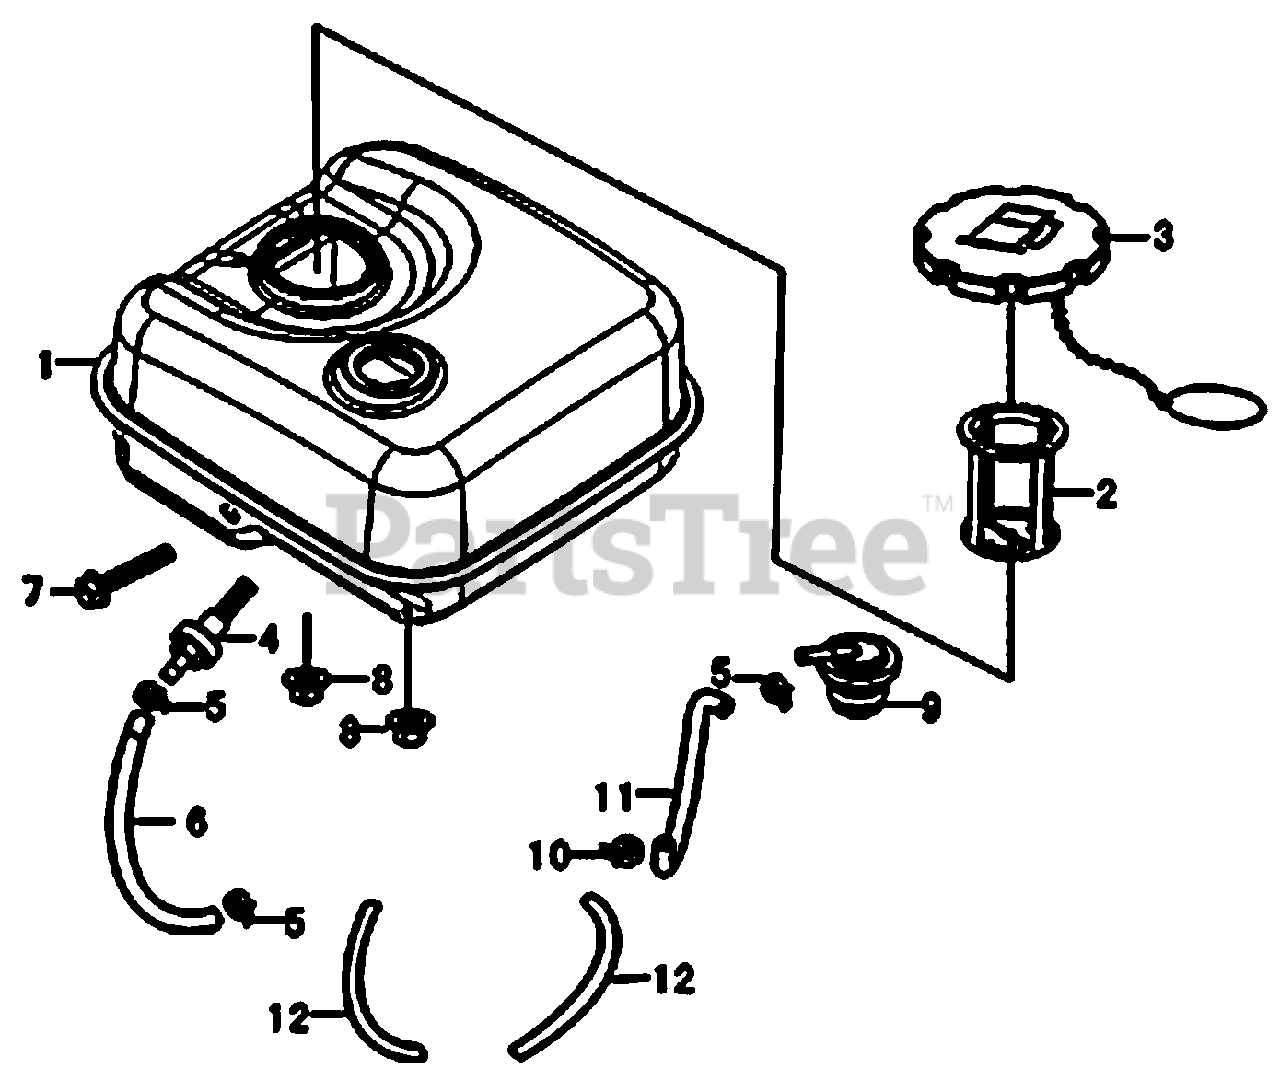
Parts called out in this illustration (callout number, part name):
1	TANK, FUEL
3	CAP, GAS, FUEL TANK
4	OUTLET SUBASSEMBLY, FUEL TANK OIL
6	TUBE, FUEL
11	HOSE, FUEL STEAM RUBBER
12	JACKET, RUBBER
